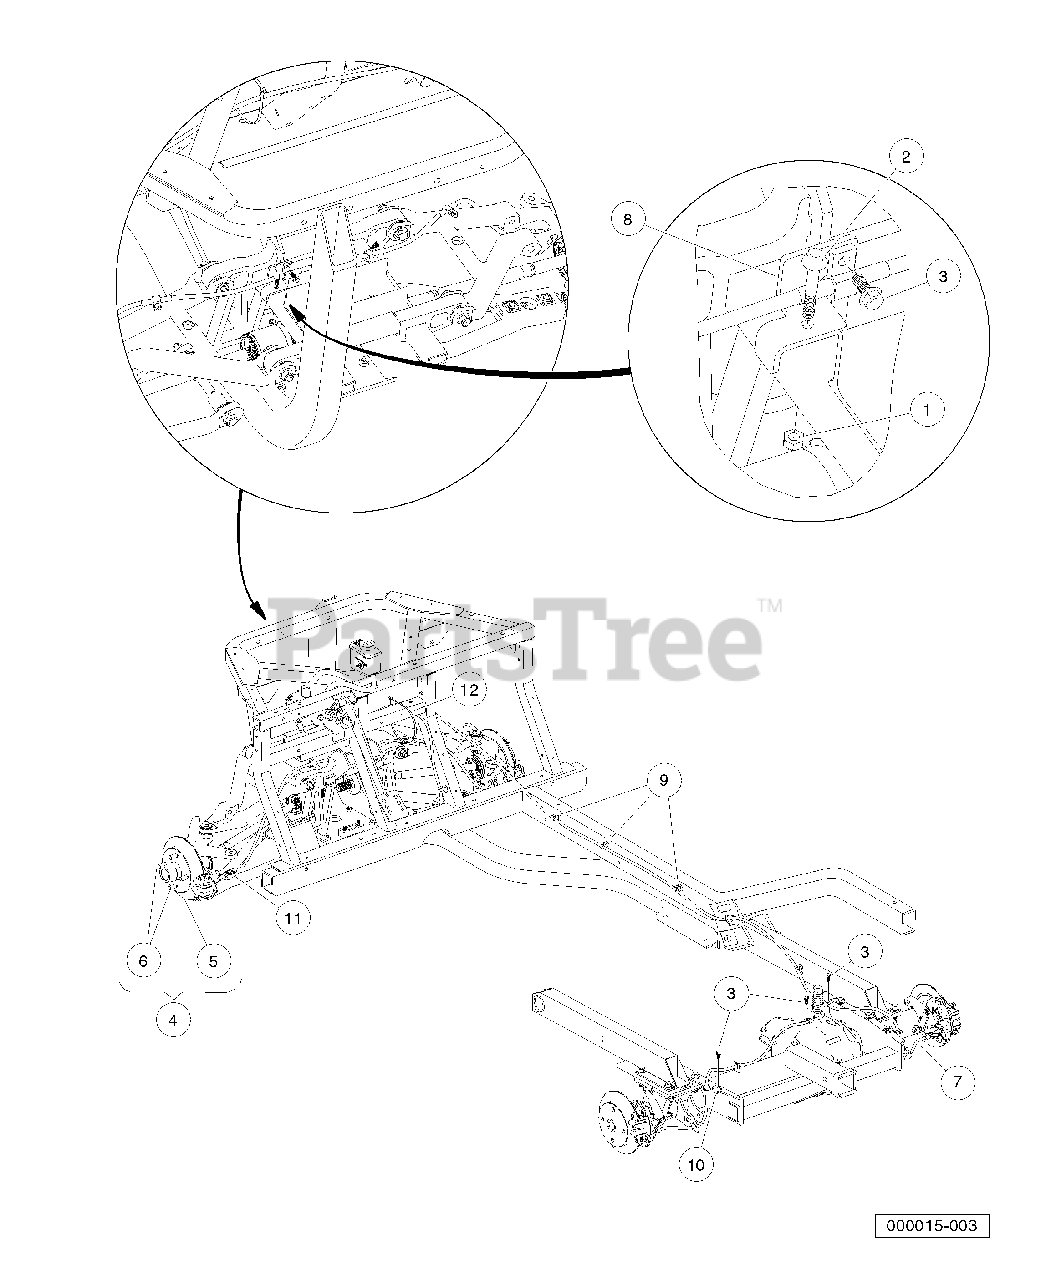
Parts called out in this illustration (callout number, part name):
1	Locknut, M6-1.00 Nylon Insert
2	Bolt, Flanged Head, M6x1.0x40
3	Screw, M6 X 16 Tt Hx Fl Hd
4	Assy, Rotor, Brake, Front, Wt
5	Rotor, Brake, Front, Wt
6	Stud, Wheel Lug
7	Assembly, Brake Line, Rear
8	Bracket, Tee, Brakeline
9	Clip, Brake Line
10	Bracket, Line, Hydraulic
11	Brakeline, Front, Assembly
12	Tie Wrap, 11" Nylon
